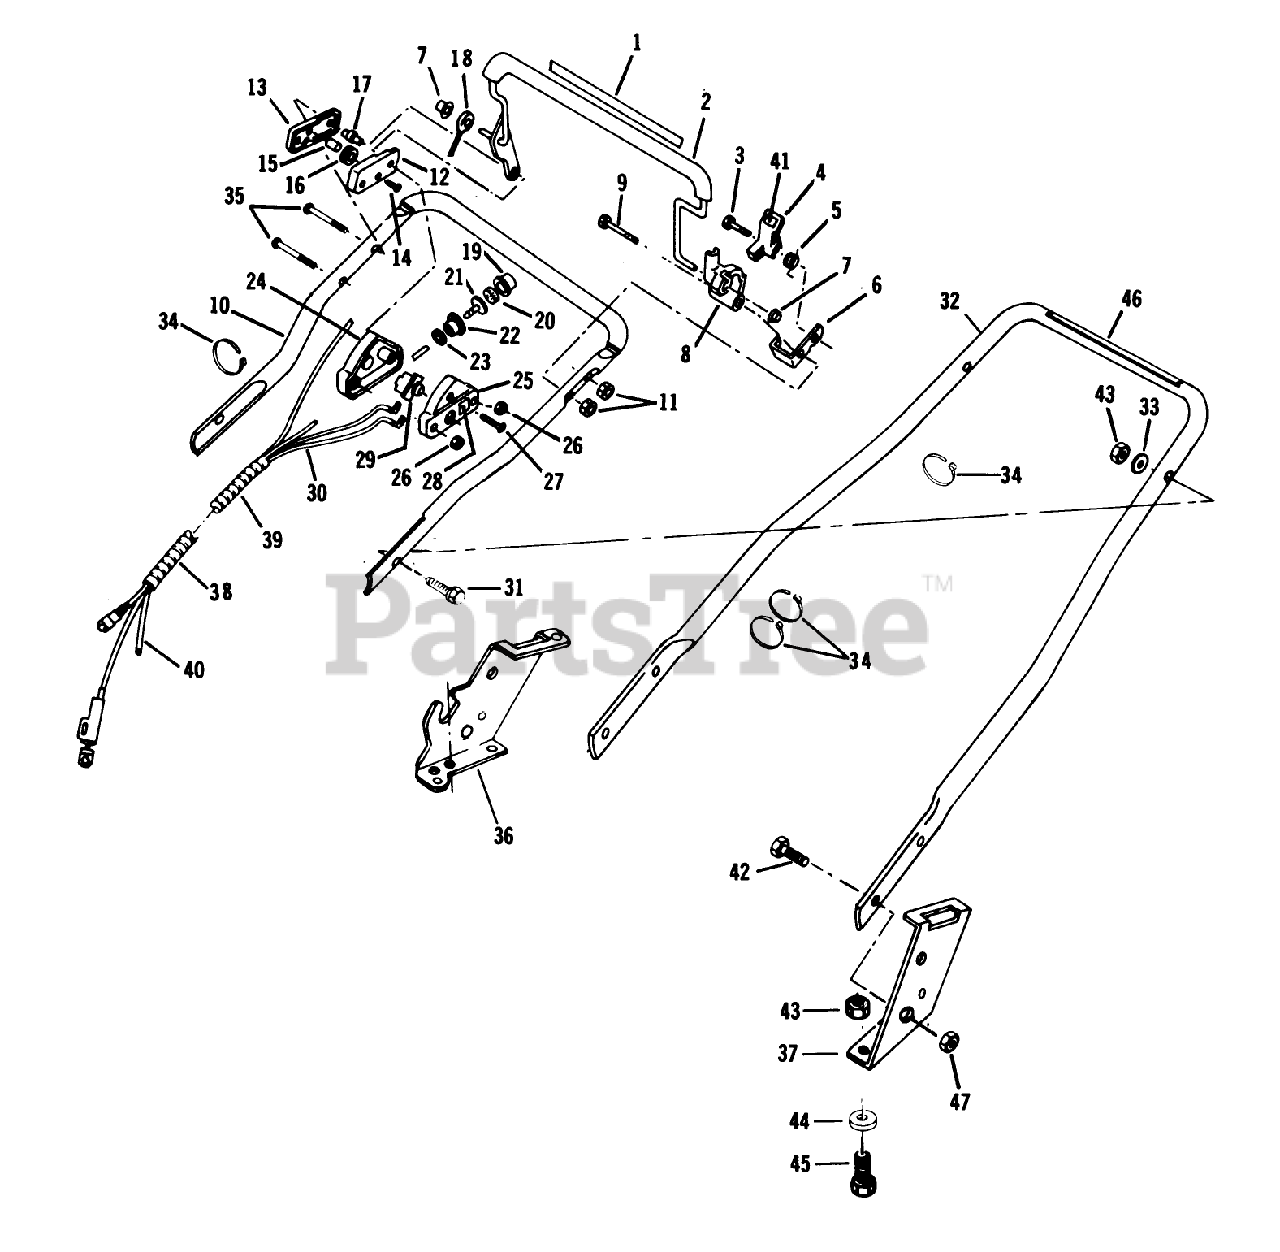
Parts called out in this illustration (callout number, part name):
9	BOLT-SHOULDER
11	LOCKNUT E
14	SCREW LAWRENCE
15	PIN SKF
17	COLUMN
20	FILTER S
23	LOCKNUT S
26	NUT C/LOCK E
27	SCREW
29	SWITCH AY
33	WASHER-CURVED
42	BOLT
43	NUT-LOCK F
44	WASHER
47	NUT-JAM, LOCKING
